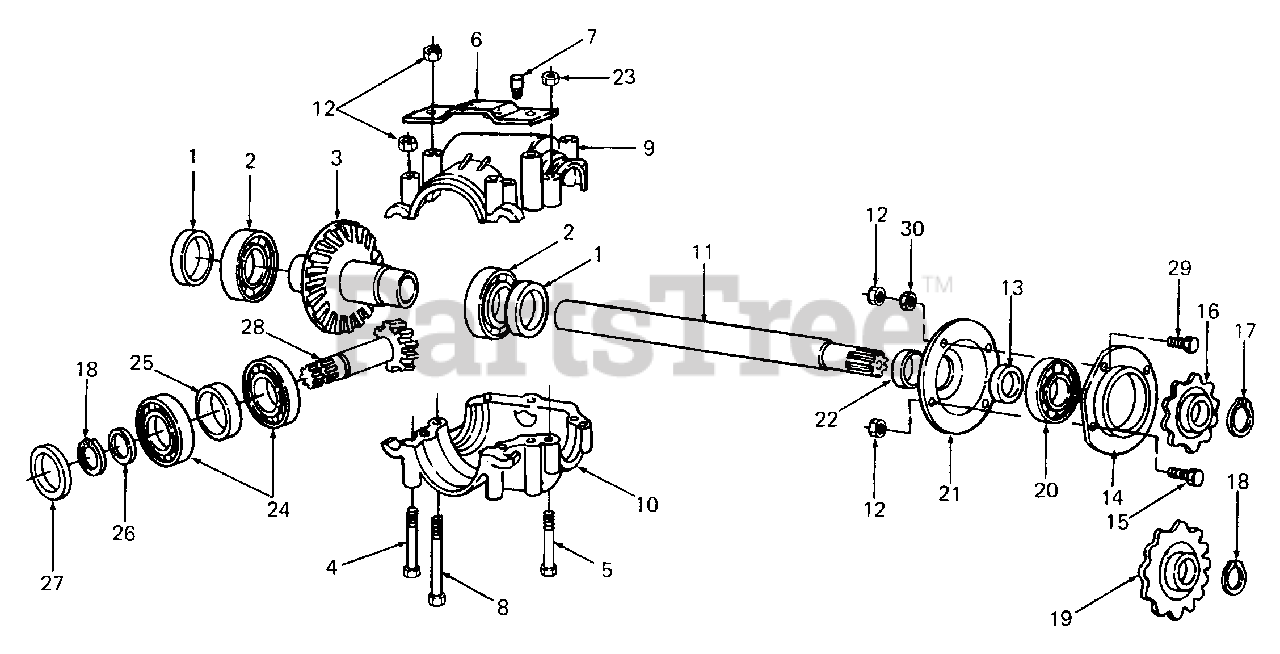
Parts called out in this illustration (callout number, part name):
3	Gear Assy, Bevel
4	Bolt, M10 X 110
5	Bolt, Socket Head, M8 X 50
7	Cap, Breather
8	Bolt, M10 X 120
9	Gear Box Top Half
10	Gear Box, Bottom Half
11	Shaft, Drive
14	Bearing Cover, Outer
15	Bolt, M10 X 25
16	Sprocket, 9 Tooth
19	Sprocket, 22 Tooth
21	Bearing Cover, Inner
25	Spacer, Bearing
26	Ring, Spacer
28	Shaft, Bevel Pinion
29	Bolt, M10 X 45
30	Nut, M12
